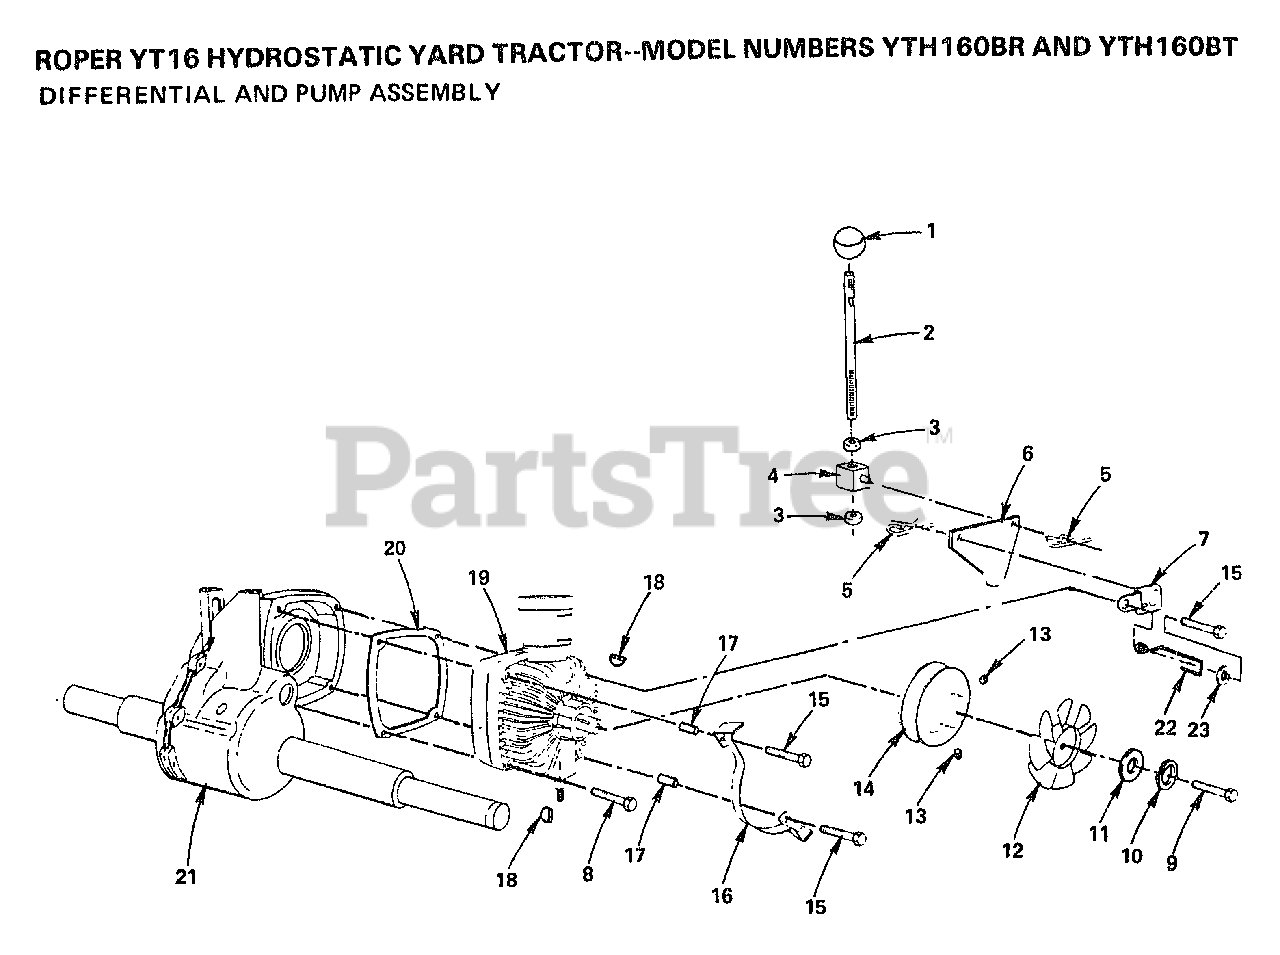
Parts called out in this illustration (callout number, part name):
1	KNOB T(3/8 HOLE)
2	ROD COAST HYT
3	NUT
4	TRUNION HYT
6	CONTROL COAST HYT
7	BRKT ASSEM HYT
8	BOLT - HEX 3/8 - 16 X 3
10	LOCKWASHER
11	WASHER
12	FAN HYDRO HYT
18	KEY T
19	PUMP HYDRO HYT
20	GASKET HYDRO HYT
23	WASHER
